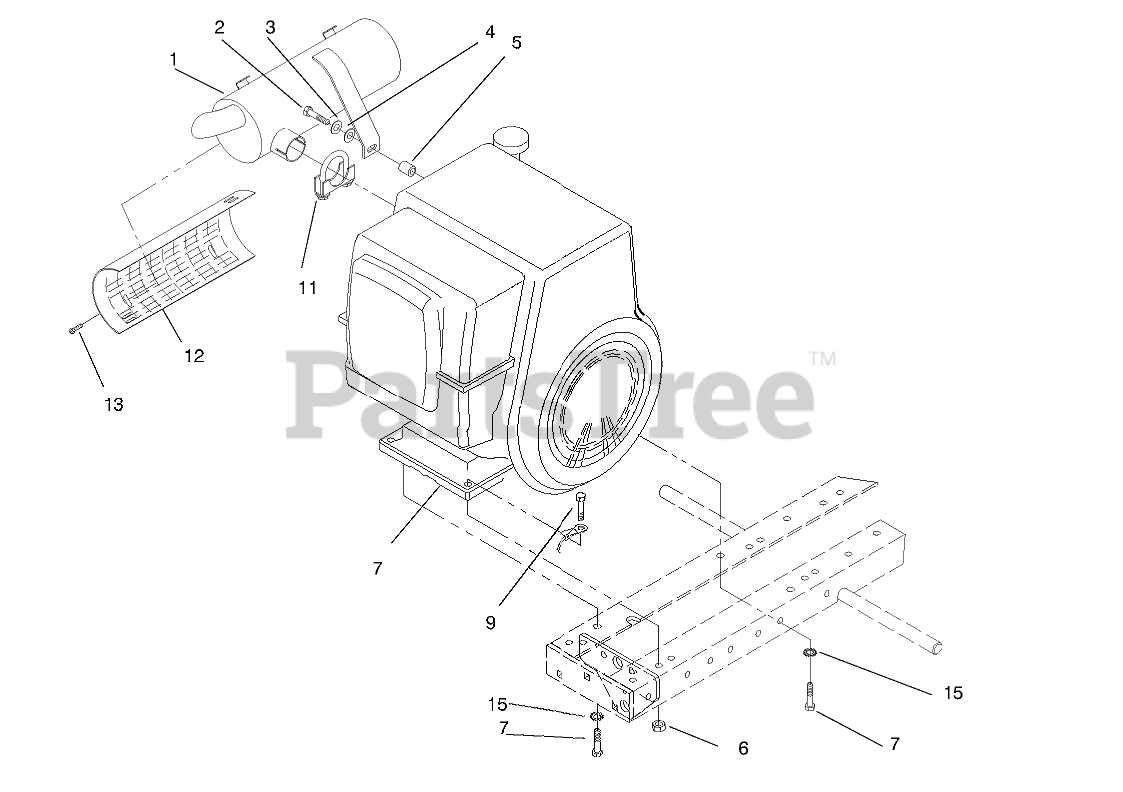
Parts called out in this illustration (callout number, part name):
1	MUFFLER
2	SCREW-HH
3	WASHER-LOCK
4	WASHER-PLAIN
5	SPACER
6	NUT-LOCK, NI
7	SCREW-HH
9	SCREW-HH
10	Engine-14HP
11	CLAMP-1 1/2
12	SHIELD-HEAT
13	SCREW
14	WIRE GROUND
15	WASHER-LOCK
